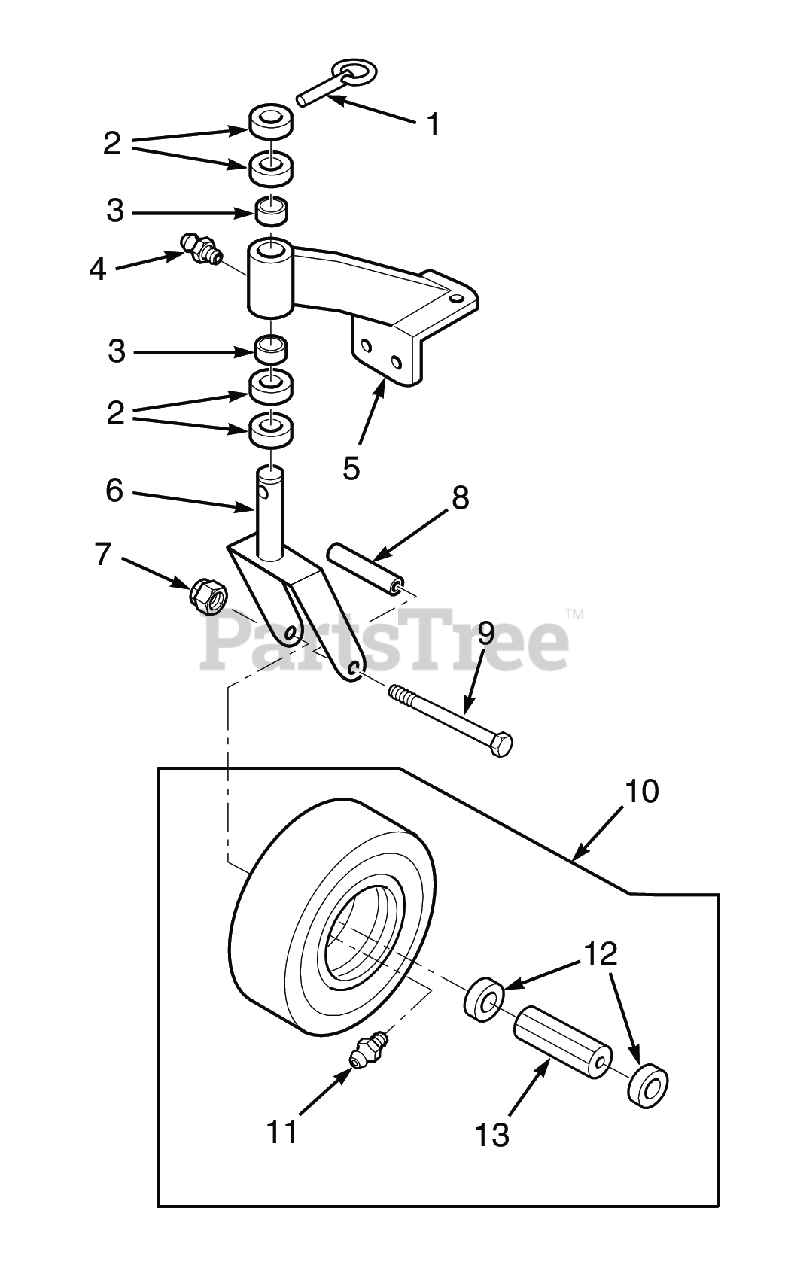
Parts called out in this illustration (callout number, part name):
1	Quick Pin, .438" Dia.
2	SPACER, CASTER YOKE, 1/2" THICK
3	Bronze Bushing, 7/8 ID x 1.0 Flanged
4	GREASE FITTING, STR. 1/4-28 SELF TAP.
5	Support Assembly
6	Caster Yoke Weldment
7	HEX LOCKNUT, ELASTIC STOP, 1/2-13
8	SLEEVE, CASTER WHEEL BEARING
9	Bolt, Hex Head 1/2-13 x 5-1/2" (Three Weights Installed)
10	REPLACED BY 9275
11	GREASE FITTING, 45 DEGREE 1/4-28
12	Retainer, Bearing, Caster Wheel
13	Roller Bearing, .625 x 3-1/4"
